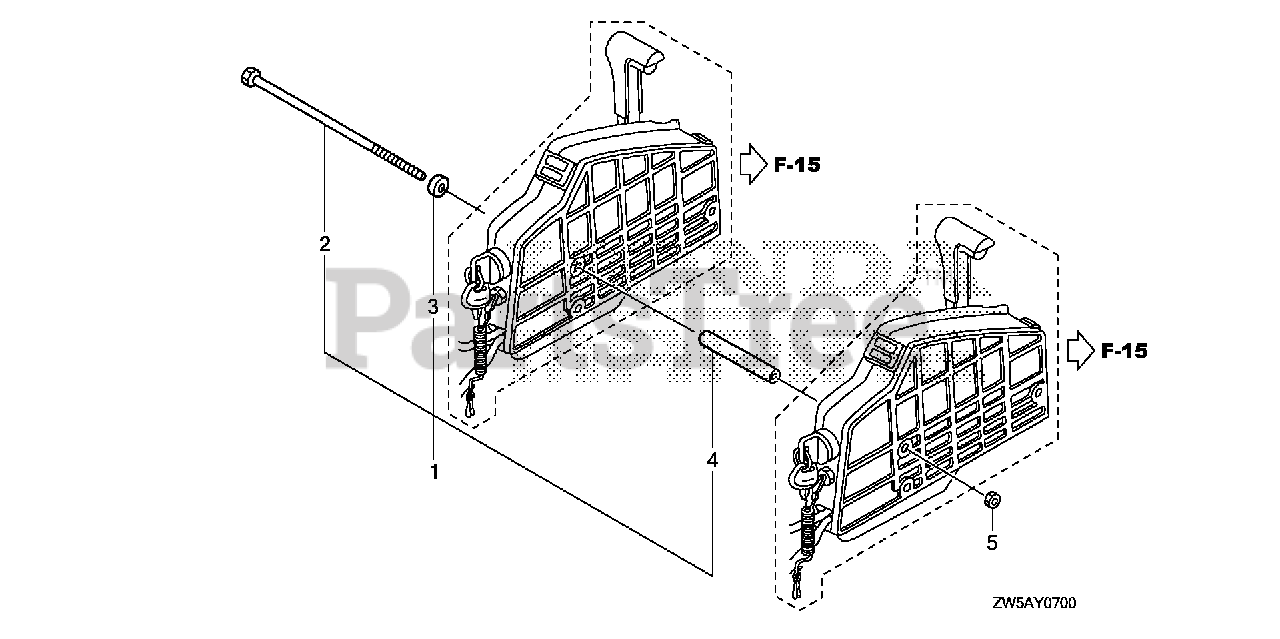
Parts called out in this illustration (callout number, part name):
1	BOLT KIT, SIDE REMOTE CONTROL
2	BOLT, SPECIAL (6X220)
3	COLLAR, DISTANCE (A)
4	COLLAR, DISTANCE (B)
5	NUT, HEX. (6MM)
